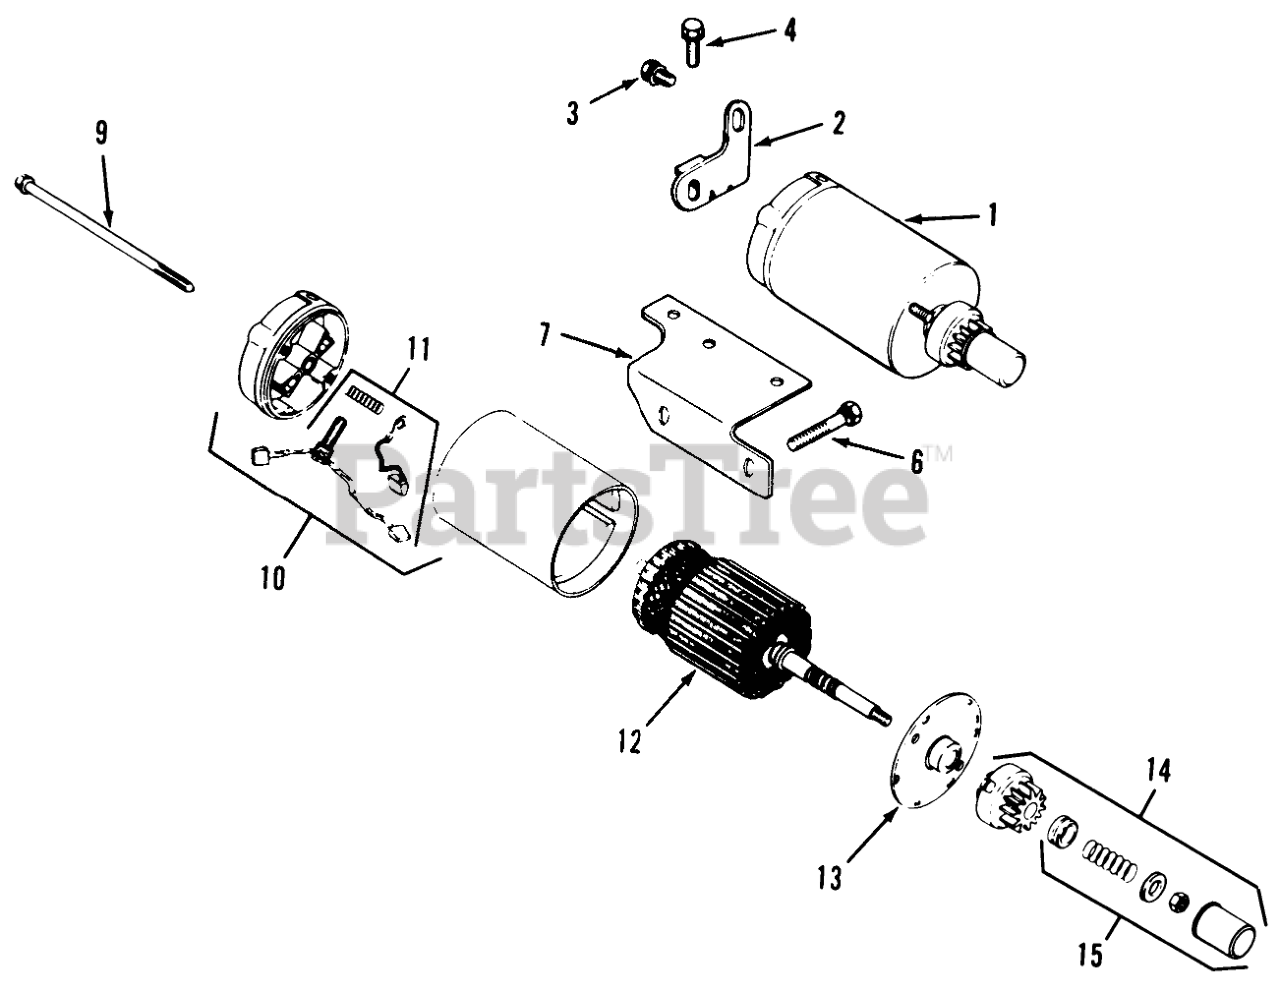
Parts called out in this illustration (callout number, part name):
1	Starter Assembly (Includes Items 9 thru 15)
2	Brace-Starter Tail
3	Screw-Hex. Hd.
4	Screw
6	Screw
7	Bracket-Starter
10	Commutator End Cap Assembly (Includes Item 11)
11	Brush Kit
12	Armature
13	Cap-Drive End
14	Drive Kit (Includes Item 15)
15	Drive Parts Kit
